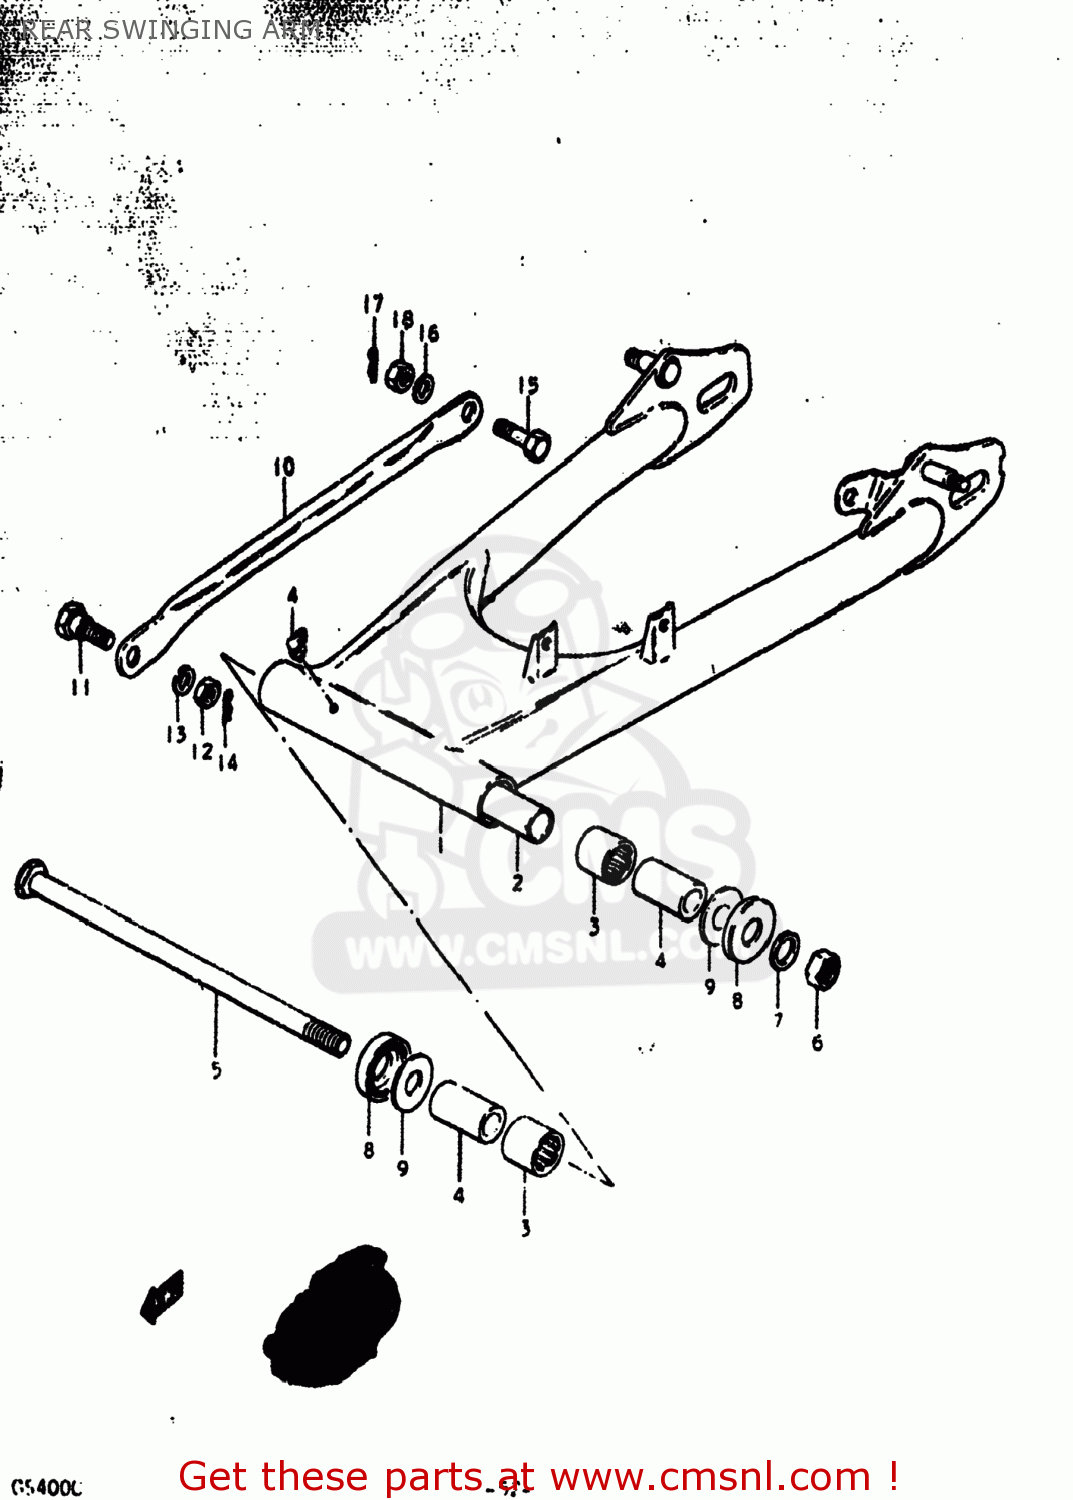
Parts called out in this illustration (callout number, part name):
1	SWING ARM ASSEMBLY,REAR
2	SPACER,SWING ARM,CENTER
3	BEARING(22X29X30)
4	SPACER,RR SWGARM PIVOT
5	SHAFT,REAR SWING ARM
6	NUT 14MM
7	WASHER
8	COVER,REAR SWING ARM DUST
9	WASHER(14.2X34X1)
10	TORQUE LINK,REAR
11	BOLT(10X24.5)
12	NUT
13	LOCK WASHER
14	CLIP
15	BOLT(10X31)
16	LOCK WASHER
17	CLIP
18	NUT
